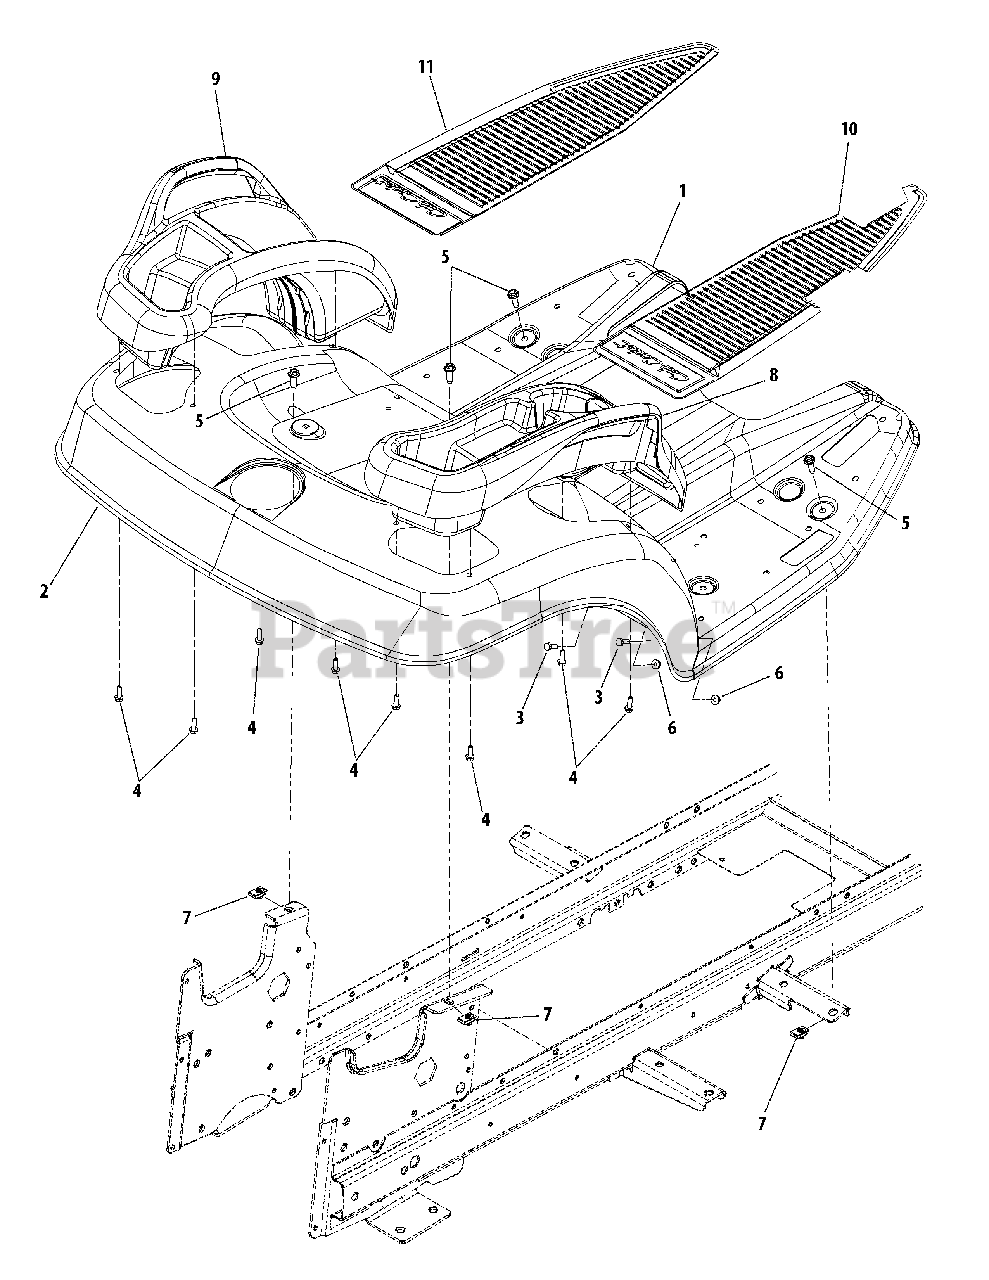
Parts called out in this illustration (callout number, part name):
1	Running Board w/Graphic
3	Screw, Hex Cap, 1/4-20 x .75 GR5
4	Screw, 1/4-15 x.750
5	Screw, Hex Wash Hd Tapp 5/16-18 x 1.0
6	Nut, Hex Flange Lock, 1/4-20
7	U-Nut, 5/16-18
8	Cover, Fender RH
9	Cover, Fender LH
10	Pad, RH Foot
11	Pad, LH Foot
